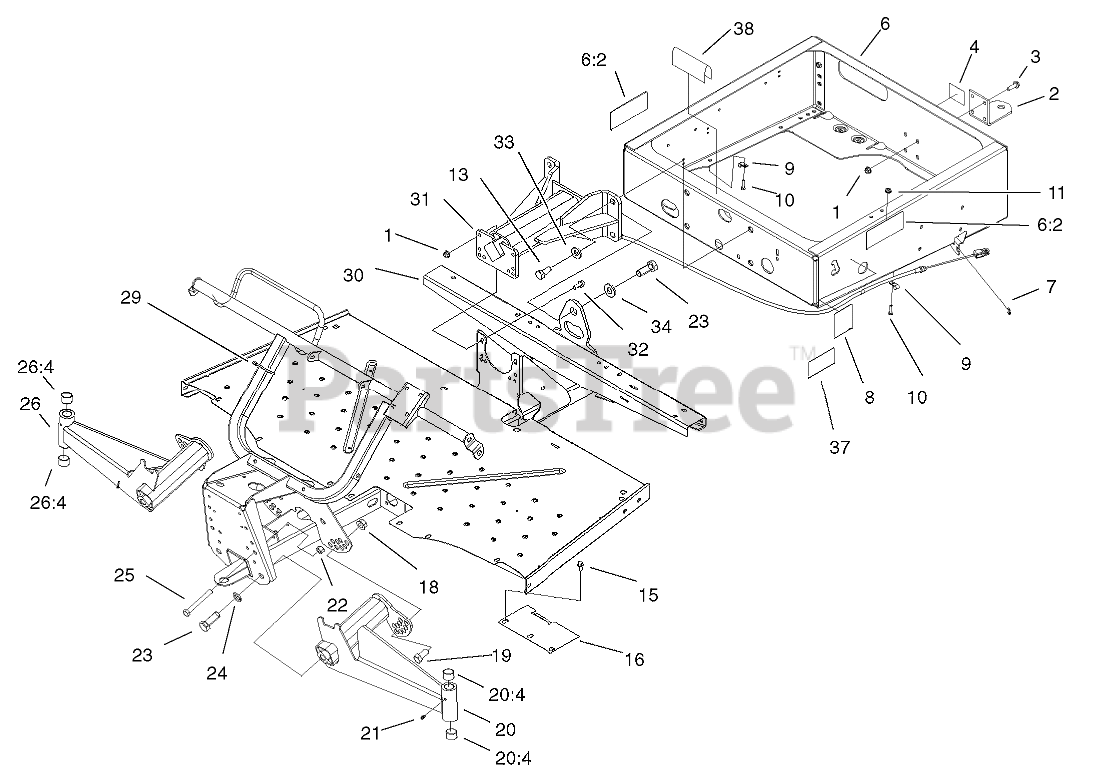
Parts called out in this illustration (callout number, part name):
1	NUT-HF, NI
2	HITCH-DUTY, LIGHT
3	SCREW-HHF
4	DECAL-RATING, HITCH (LIGHT DUTY)
6	REAR FRAME ASM
6:2	DECAL-WARNING
7	RING-RETAINING, EXTERNAL
8	DECAL-INFORMATION, BOXLATCH
9	CLAMP-R
10	SCREW-HH
11	NUT-HF
13	SCREW-HH
15	SCREW-HHF
16	COVER-PEDAL
18	NUT-HF
19	SCREW-HH
20	LH A-ARM ASM
20:4	BUSHING
21	FITTING-GREASE
22	NUT-LOCK, NI
23	SCREW-HH
24	WASHER-LOCK, INT
25	SCREW-HH
26	RH A-ARM ASM
26:4	BUSHING
29	TIE-CABLE
30	FRAME-FRONT
31	PIVOT YOKE ASM
32	SCREW-HHF
33	WASHER-FLAT
34	WASHER-HARDENED
37	DECAL-CAPACITY (CE)
